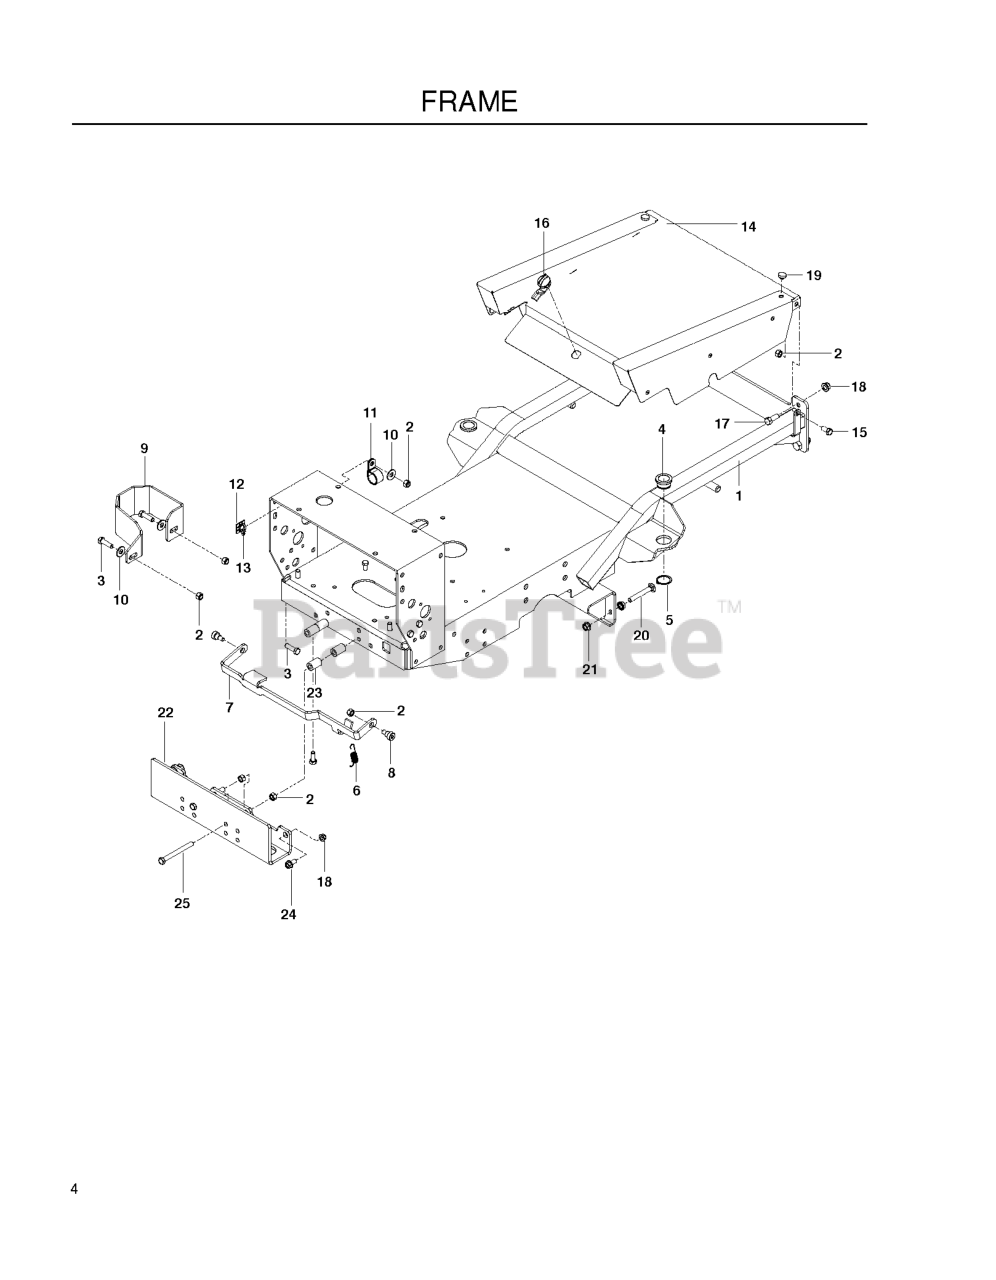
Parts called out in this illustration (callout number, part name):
1	CHASSIS WLDT ORANGE
2	NUT 3/8-16 NYLOC
3	HCS 3/8C X 1 1/4 GR5
4	BUSHING, BRONZE HOC
5	SNAP RING 1.25
6	SPRING, EXTENSION
7	BAR, THROWOUT OR
8	SB 3/8-16 X 3/8 SKT HD ZD
9	GUARD FILTER PAINTED
10	WASHER 3/8 FLAT
12	MOUNTING BLOCK CABLE TIE
13	TIE, PLASTIC
14	COVER, ASM, CENTER
15	SCREW 3/8C X 3/4 HEX CAP
16	LATCH, SHORT WING
17	HCS 1/2-13 X 1-1/4
18	NUT, 1/2-13 HEX FLG NYLOC ZD
19	GROMMET, BUMPER
20	RHSNB 3/8-16 x 2¾
21	NUT 3/8C WHIZ
22	BUMPER, OR
24	HHFS 1/2-13 X 1 GR5 ZD
25	HCS3/8-16.X
